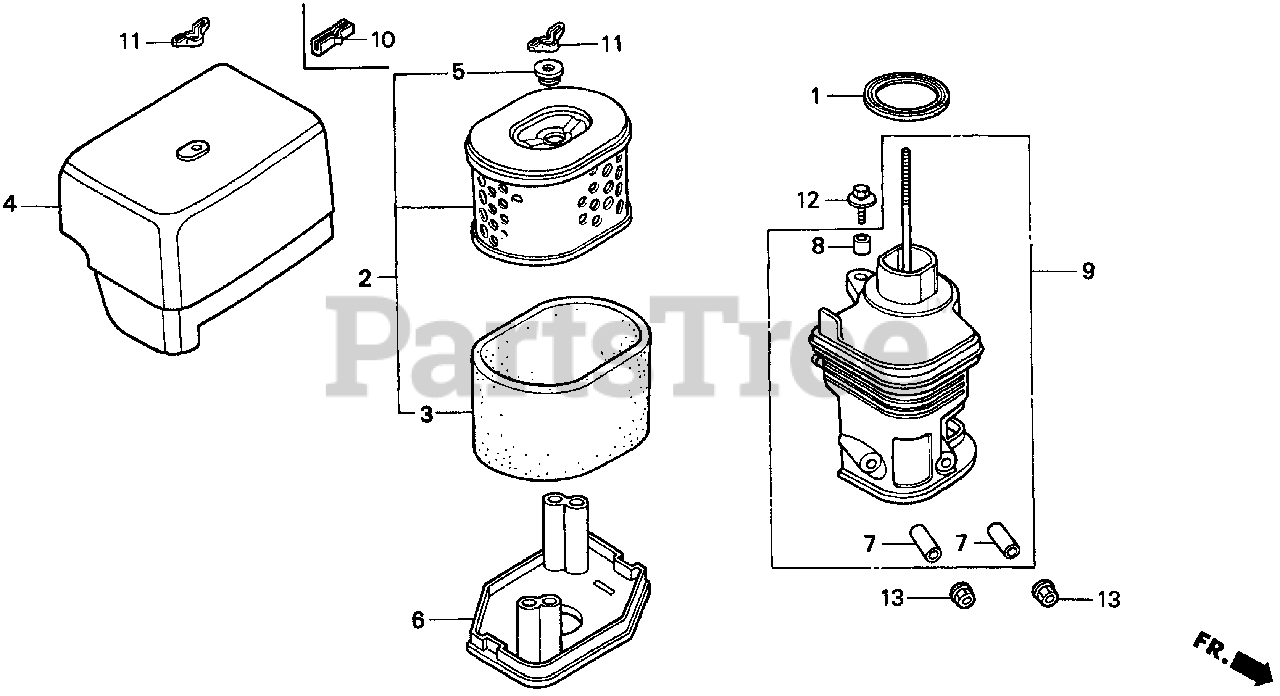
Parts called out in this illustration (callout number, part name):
1	GASKET, ELBOW
2	ELEMENT, AIR CLEANER
3	FILTER (OUTER)
4	COVER, AIR CLEANER
5	GROMMET, AIR CLEANER
6	NOSE, MUFFLER
7	COLLAR, AIR CLEANER
8	COLLAR B, AIR CLEANER
9	ELBOW, AIR CLEANER
11	WINGNUT, TOOL BOX SETTING
12	BOLT-WASHER (6X22)
13	NUT, FLANGE (6MM)
